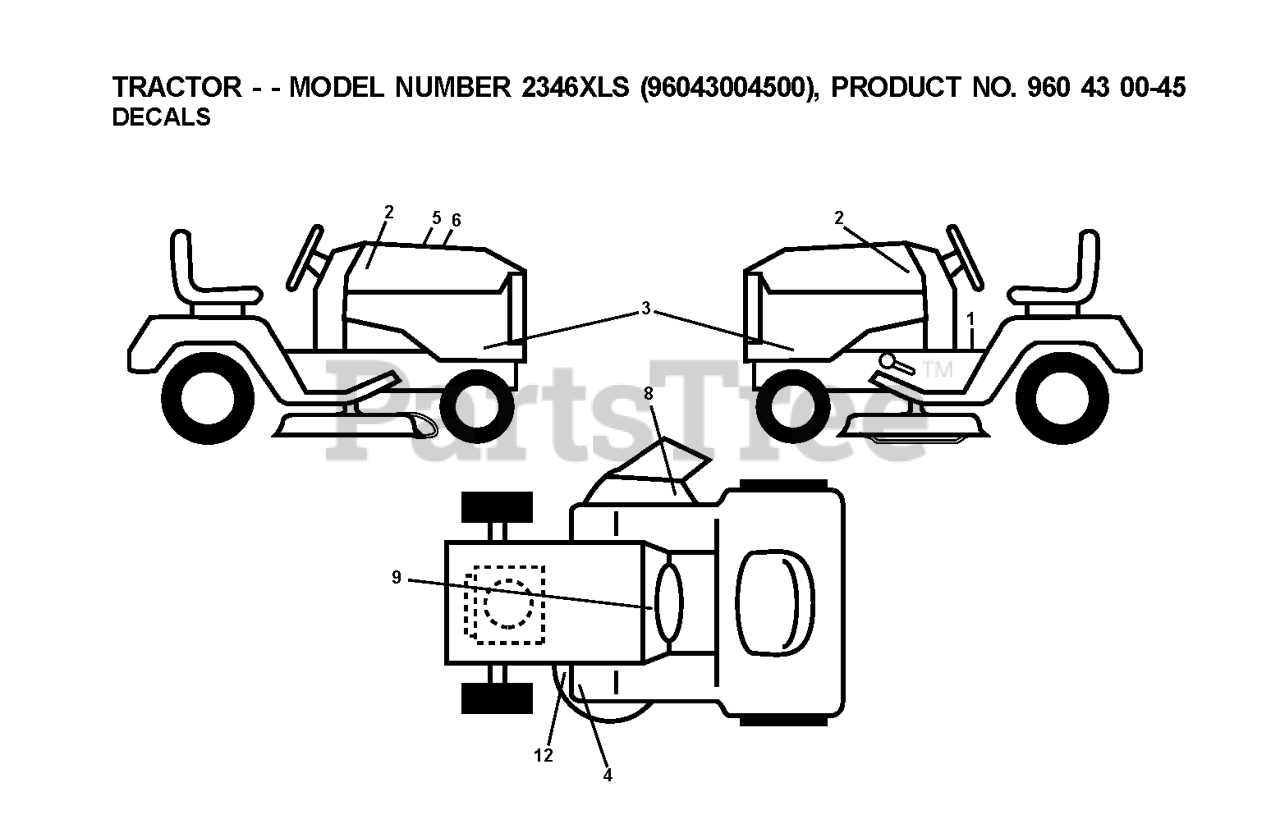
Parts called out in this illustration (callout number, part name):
1	DECAL.FENDER.WARNING.ENG
2	EMBLEM.HOOD.HUSQ.DEALER
3	DECAL.SDPNL.2346XLS.VANGRD.HU
4	DECAL.PEDAL.HUSQ.CROWN
5	DECAL HOOD CUST. RESP.
6	DECAL.RPL.BSM38.VAGD.TLW46K46
8	DECAL.WARN.KEEP.HAND.AWAY
9	DECAL BTRY SYMBOLS
12	DECAL V BELT SCHEMATIC
